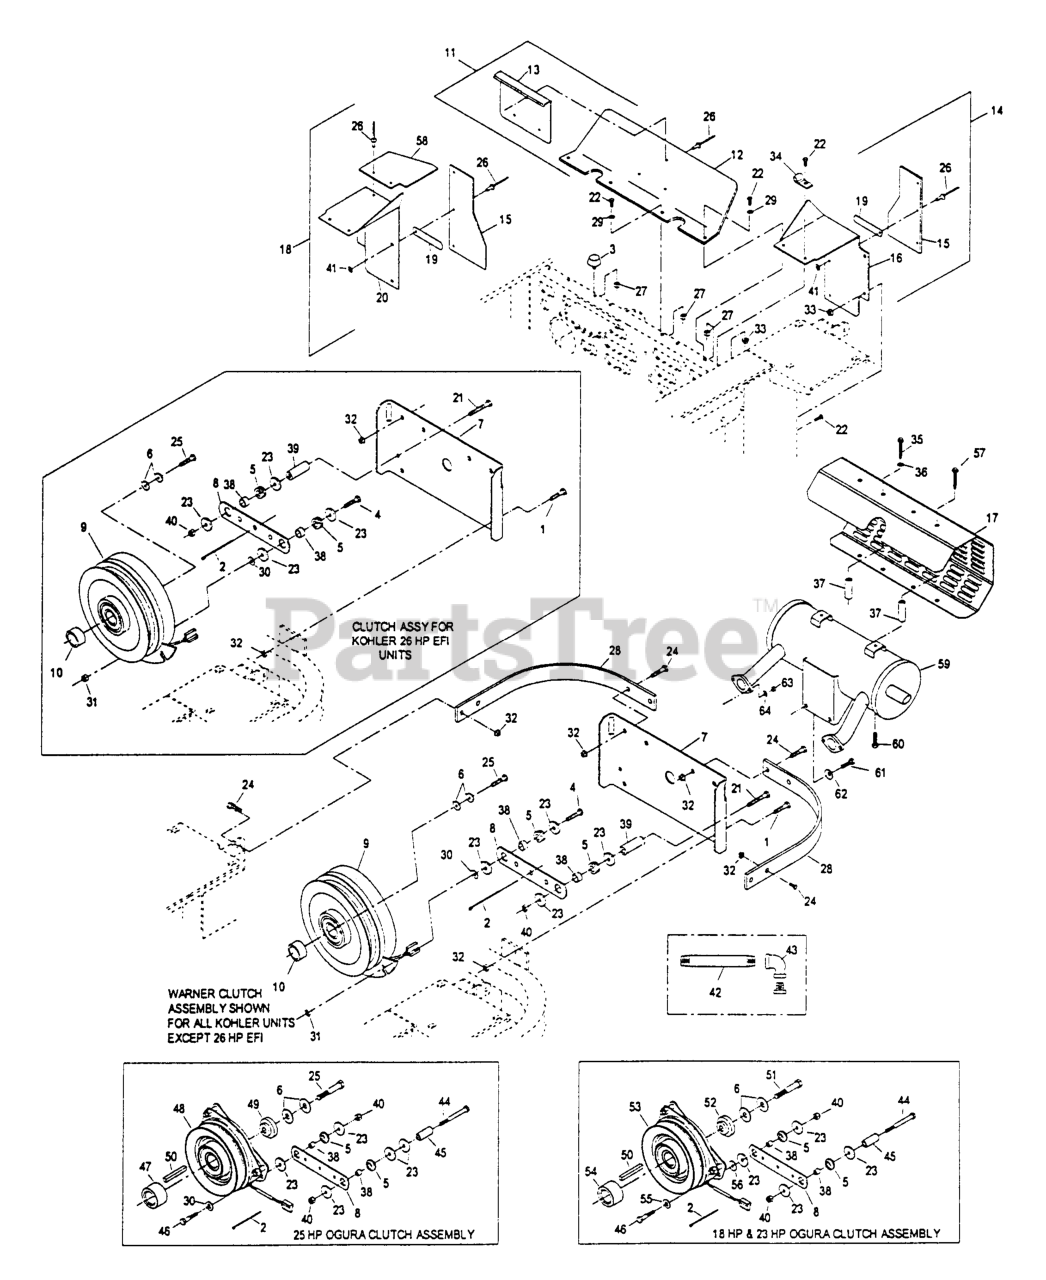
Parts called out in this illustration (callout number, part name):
2	TIE-PLASTIC
5	GROMMET
6	WASHER-SPRING
7	GUARD-CLUTCH
8	STRAP-CLUTCH, BRAKE
10	SPACER-CLUTCH
13	Shield, Lift
15	SHIELD-ENGINE
18	RH SHIELD ASM
19	CLIP-BAFFLE, REAR
26	RIVET-POP
34	CLIP-LOOM
36	WASHER-SPRING
39	SPACER-ANCHOR, CLUTCH
42	NIPPLE
43	ELBOW-90 DEG
45	BUSHING-LEVER, LIFT
47	SPACER,CLUTCH
49	KEEPER,CLUTCH
50	KEY,MACH HRD
53	Clutch W/Tie (18 & 23hp Ogura)
54	SPACER,CLUTCH
57	SCREW-HWH
58	BAFFLE-COOLER, ENGINE
64	WASHER-LOCK
